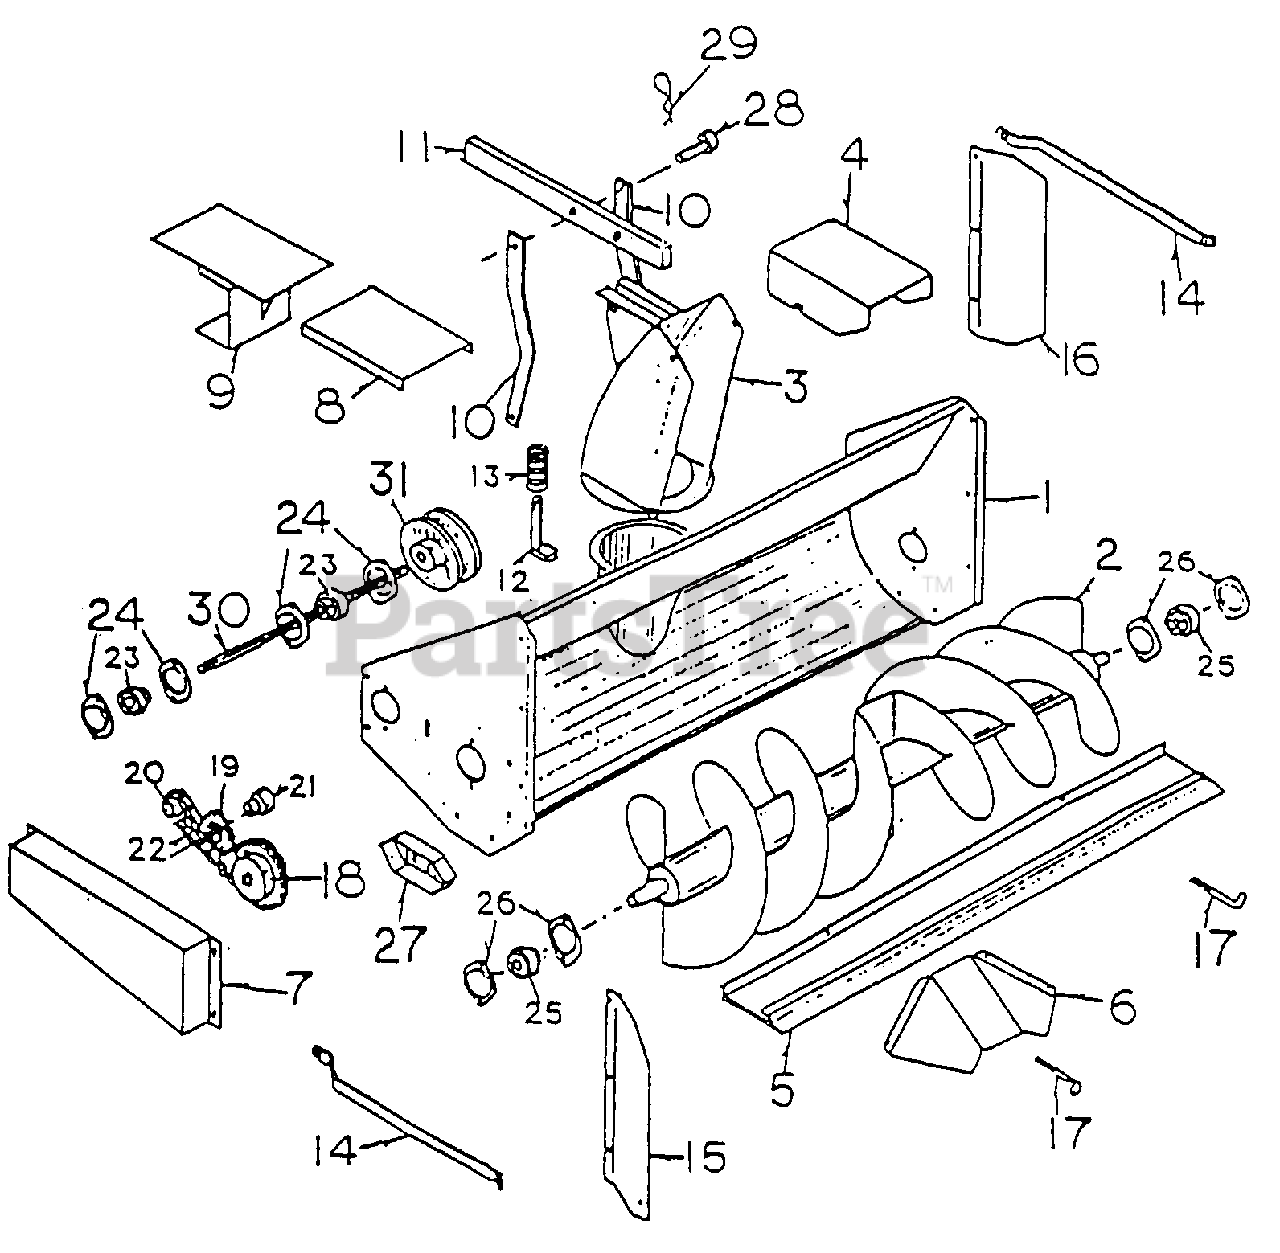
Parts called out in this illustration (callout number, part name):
1	SNOW BLOWER HOUSING
2	AUCER
3	CHUTE
4	SNO'W DEFTECInvR
7	CHAIN GUARD
8	BELT GUARD
9	BELT RETAINER
10	CHUTE LOCK LINKAGE
11	HANDLE
12	CUTE LOCK
13	CHUTE LOCK SPRINC
14	EXTENDER BRACES
15	R.H. EXTENDER
17	BLADE B0LT
18	AUGER SPROCKET
19	IDLER SPROCKET
20	DRIVE SPROCKET
21	IDLER SPROCKET BUSHING
24	3/4 BEARING FLANGE
25	lin. BEARING
26	lin. BEARING FLANGE
30	SHIFT
